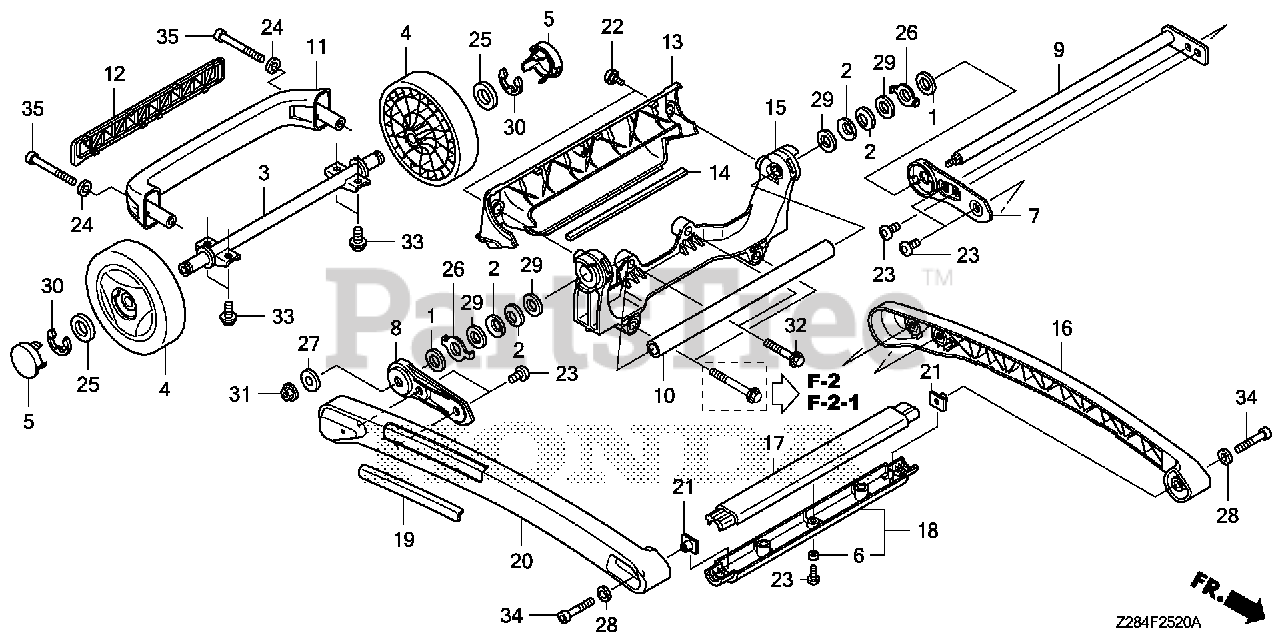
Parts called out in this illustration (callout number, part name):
1	WASHER, FRICTION
2	SPRING, FRICTION
3	SHAFT, WHEEL
4	WHEEL (140X35) *NH246* (LOOSY GRAY)
4	WHEEL (140X35) *NH246* (COO) (LOOSY GRAY)
5	CAP, WHEEL *NH246* (LOOSY GRAY)
6	COLLAR (6X4)
7	HOLDER, R. HANDLE (NOT AVAILABLE)
7	HOLDER, R. HANDLE (COO)
8	HOLDER, L. HANDLE (NOT AVAILABLE)
8	HOLDER, L. HANDLE (COO)
9	SHAFT, HANDLE HOLDER
10	PIPE, HANDLE
11	GRIP, RR. CARRY
11	GRIP, RR. CARRY (COO)
12	COVER, RR. GRIP
13	COVER, HANDLE CARRY *NH314* (CONDUCT GRAY)
14	SEAL, HANDLE COVER
15	BASE, HANDLE
16	HANDLE, R. CARRY
16	HANDLE, R. CARRY (COO)
17	GRIP, CARRY (UPPER)
17	GRIP, CARRY (UPPER) (COO)
18	GRIP, CARRY (LOWER)
18	GRIP, CARRY (LOWER) (COO)
19	PLATE, CARRY HANDLE
20	HANDLE, L. CARRY
20	HANDLE, L. CARRY (COO)
21	NUT, RR. FENDER
22	SCREW, SPECIAL (6X12)
23	SCREW, PAN (6X12)
24	WASHER, RR. COVER GROMMET
25	WASHER (14.2MM)
26	WASHER B, FRICTION SETTING
27	WASHER, PLAIN (6MM)
28	WASHER, PLAIN (6MM)
29	WASHER (12MM)
30	E-RING (12MM)
31	NUT, FLANGE (6MM)
32	BOLT, FLANGE (6X35)
33	BOLT, FLANGE (8X16) Use from Engine SN 1000016.
34	BOLT, SOCKET (6X32)
35	BOLT, SOCKET (6X60)
